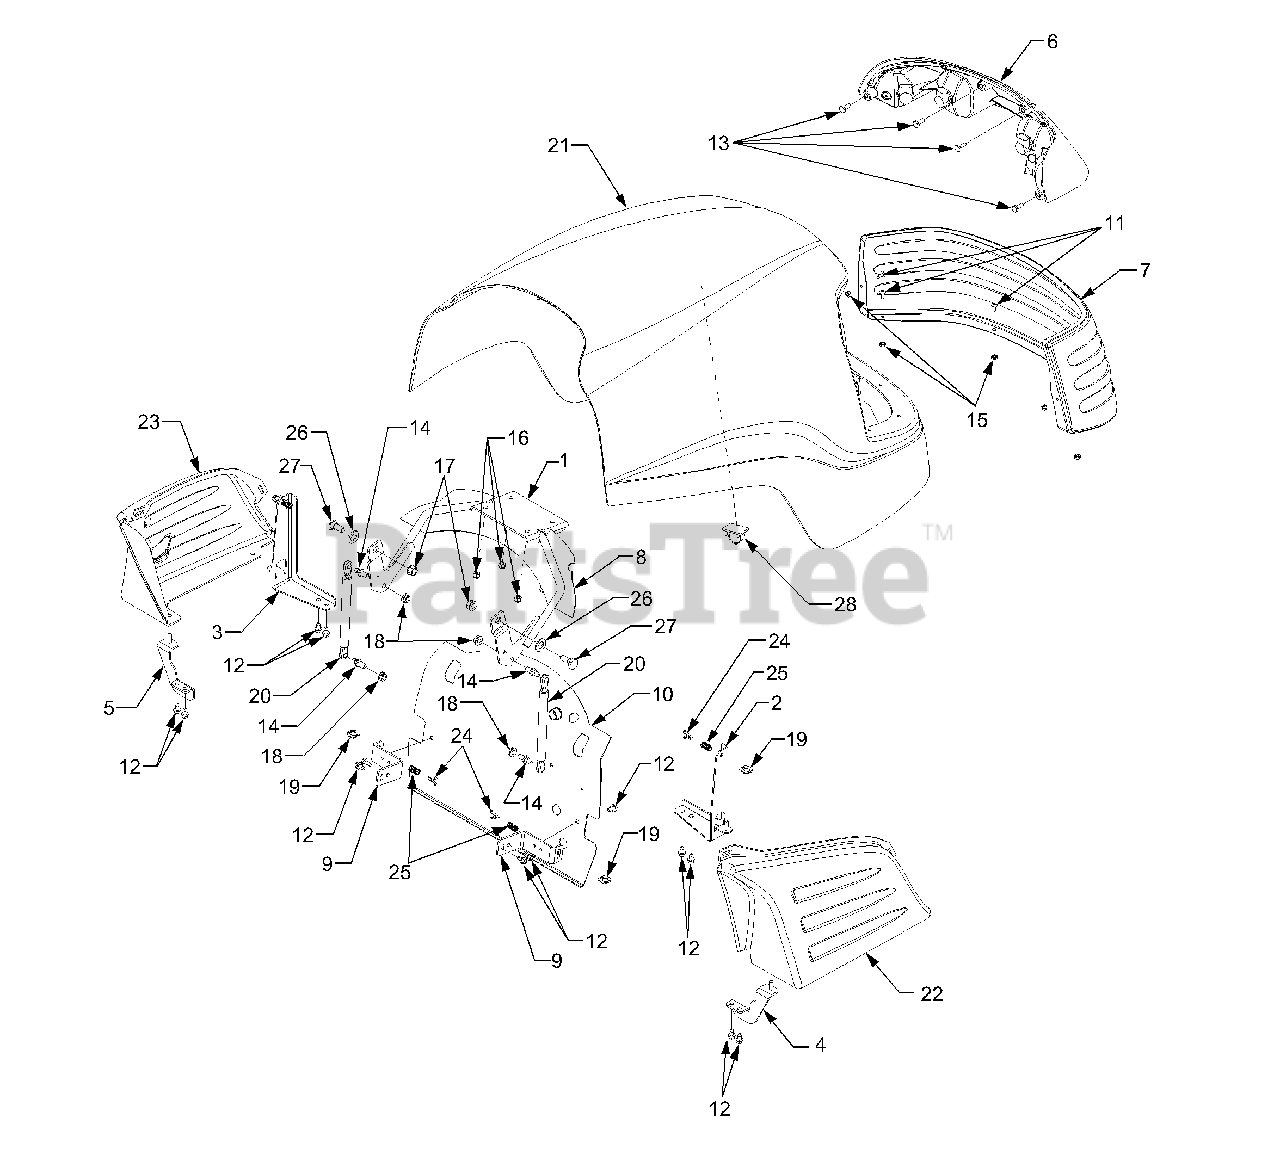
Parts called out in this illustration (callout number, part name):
1	Hinge Assembly, Hood
2	Bracket, Side Panel Mtg. RH
3	Bracket, Side Panel Mtg. LH
4	Bracket, Side Panel Mtg. RH Rear
5	Bracket, Side Panel Mtg. LH Rear
6	Headlight Assembly
9	Bracket, Panel Mtg.
10	Shield, Lower Heat
11	Screw, Truss Hd, 10-24 x .5
12	Screw, Hex Wash Hd Tapp 1/4-20 x .5
13	Screw, Hex Cap, 1/4-20 x .62 GR5
14	Stud, Cylinder, 5/16-18 Thrd
15	Nut, Hex Sems, 10-24
16	Nut, Hex Nylon Insert Lock, 1/4-20
17	Nut, Hex Flange Lock, 3/8-16
18	Nut, Hex Flange Lock, 5/16-18
19	Latch, 1/4 Turn Panel
20	Cylinder, Gas Spring
21	Hood, Service Kit
21	Hood
22	Panel, Side RH
23	Panel, Side LH
24	Clip, Spring
25	Spring, Compression
26	Washer, Flat, .510 x .1.0 x .060
27	Screw, Shoulder, .5 x .27 Lg 3/8-16
28	Clip, Retaining
